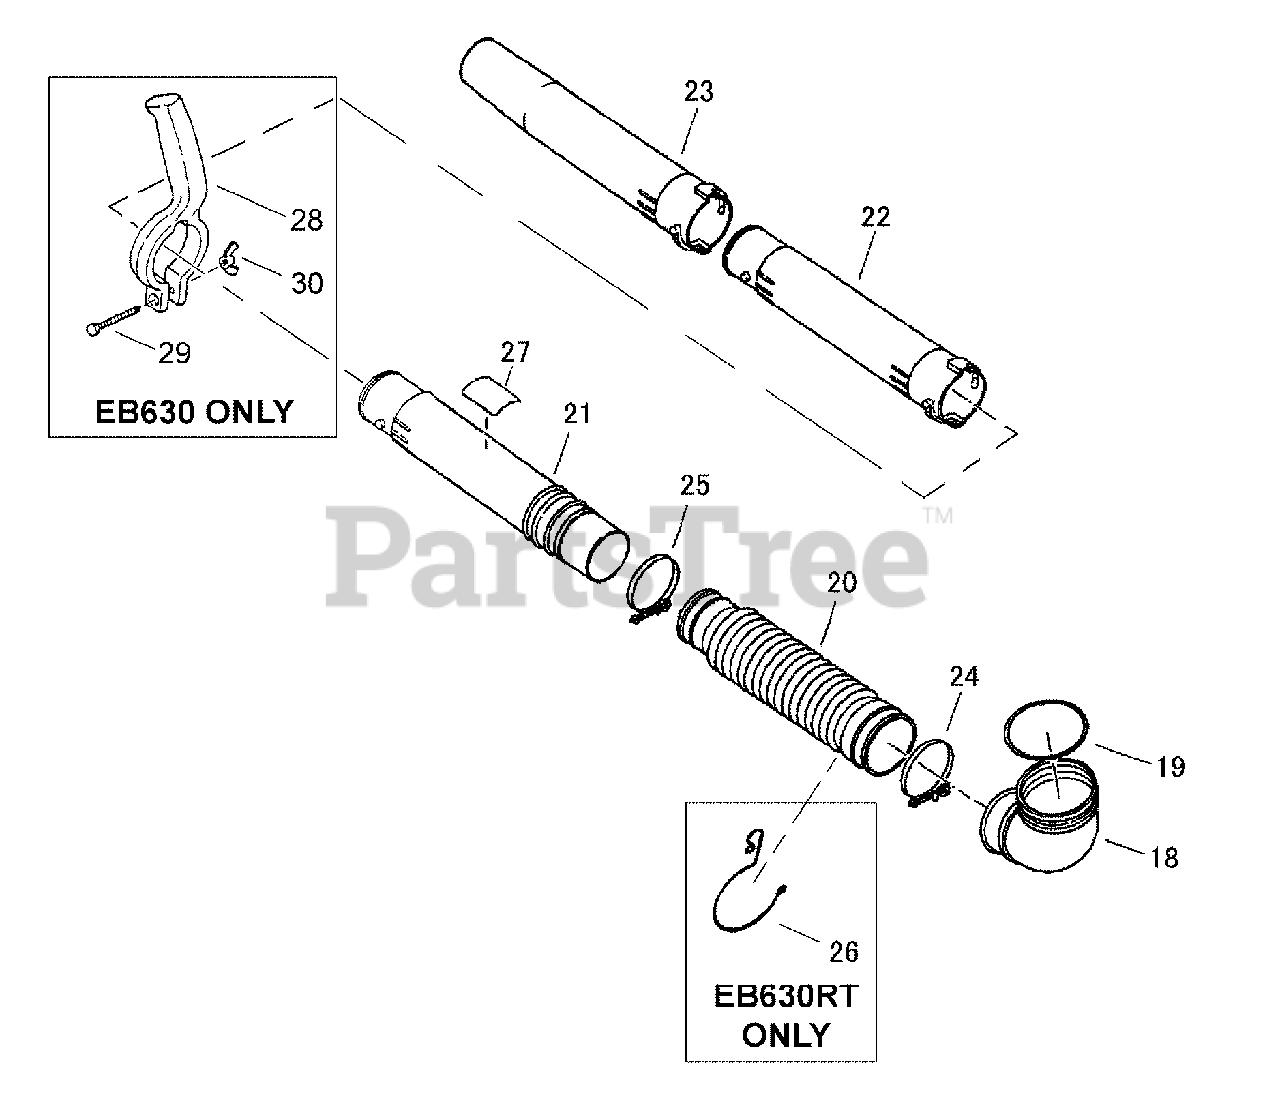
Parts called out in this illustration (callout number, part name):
18	TUBE, BLOWER - ELBOW
19	O-RING
20	TUBE, FLEXIBLE
21	TUBE, BLOWER - SWIVEL
22	TUBE, BLOWER - STRAIGHT
23	NOZZLE
24	CLAMP Ø100
25	CLAMP Ø85
26	HOLDER, THROTTLE CABLE
27	LABEL, MODEL
